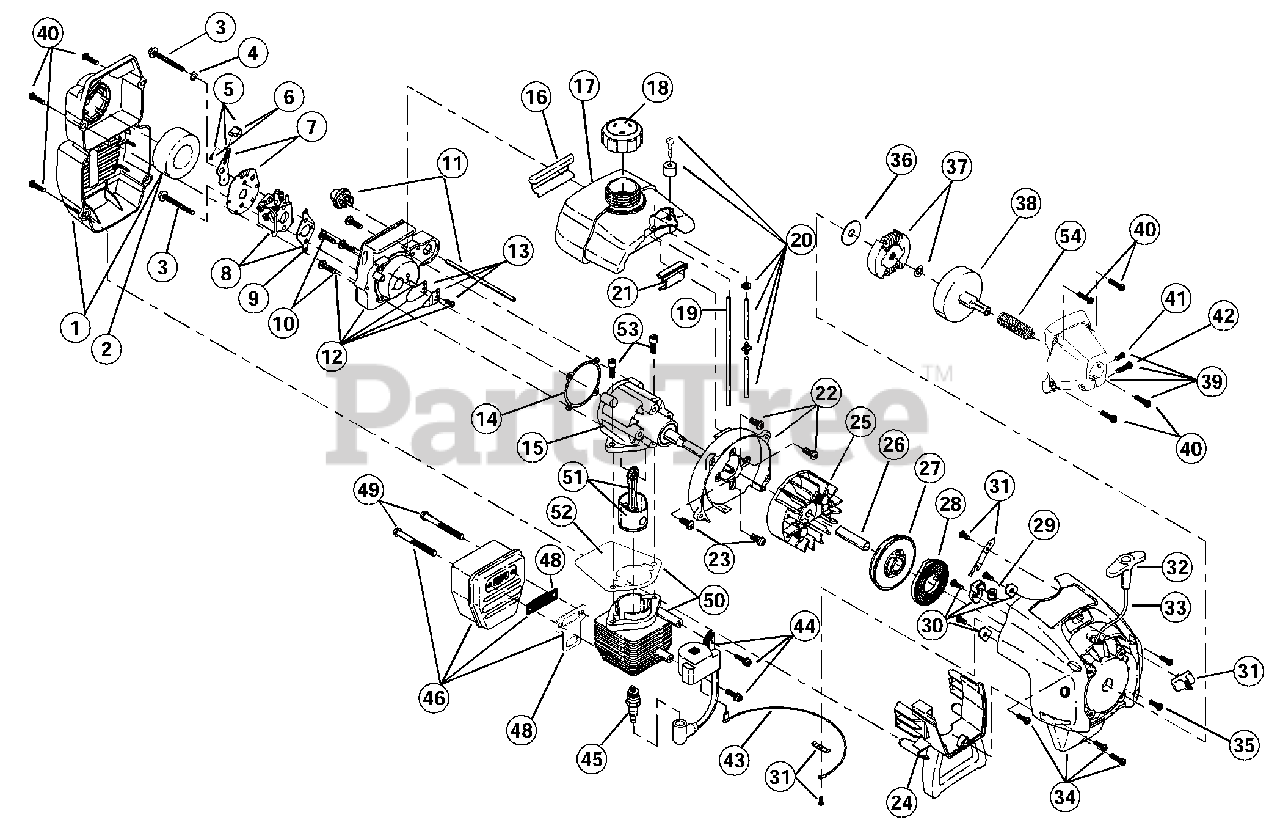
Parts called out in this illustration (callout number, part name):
1	Air Cleaner/Muffler Cover Assembly
2	Air Cleaner Filter
3	Carburetor Mounting Screw Assembly
4	Wavey Washer
5	Choke Lever Assembly
6	Choke Knob and Screw
7	Choke Lever and Plate
8	Carburetor Assembly
9	Carburetor Gasket
10	Carb Mount Screw
11	Primer and Hose Assembly
12	Carb Mount Assembly
13	Reed Assembly
14	Carburetor Mount Gasket
15	Crank Case Service Assembly
16	Rear Mounting Pad
17	Fuel Tank Assembly
18	Fuel Cap Assembly
19	Fuel Return Line
20	Fuel Line Assembly
21	Front Mounting Pad
22	Shroud Assembly
23	Shroud Screw
24	Shroud Extension and Stand
25	Flywheel Assembly
27	Recoil Pulley Assembly
28	Recoil Spring
29	Rope Guide
30	Pulley Retainer Assembly
31	Switch Assembly
32	Pull Handle
34	Starter Housing Assembly
35	Housing Screw
36	Clutch Washer
37	Clutch Rotor Assembly
38	Clutch Drum Assembly
39	Clutch Cover Assembly
40	Cover Screw
41	Anti-Rotation Screw
42	Clamping Screw
43	Wire Lead
44	Module Assembly
45	Spark Plug
46	Muffler Assembly
47	Spark Arrestor Screen
48	Exhaust Gasket
49	Muffler Mounting Bolt Assembly
50	Cylinder Assembly
51	Piston and Rod Assembly
52	Cylinder Gasket
53	Cylinder Bolt
